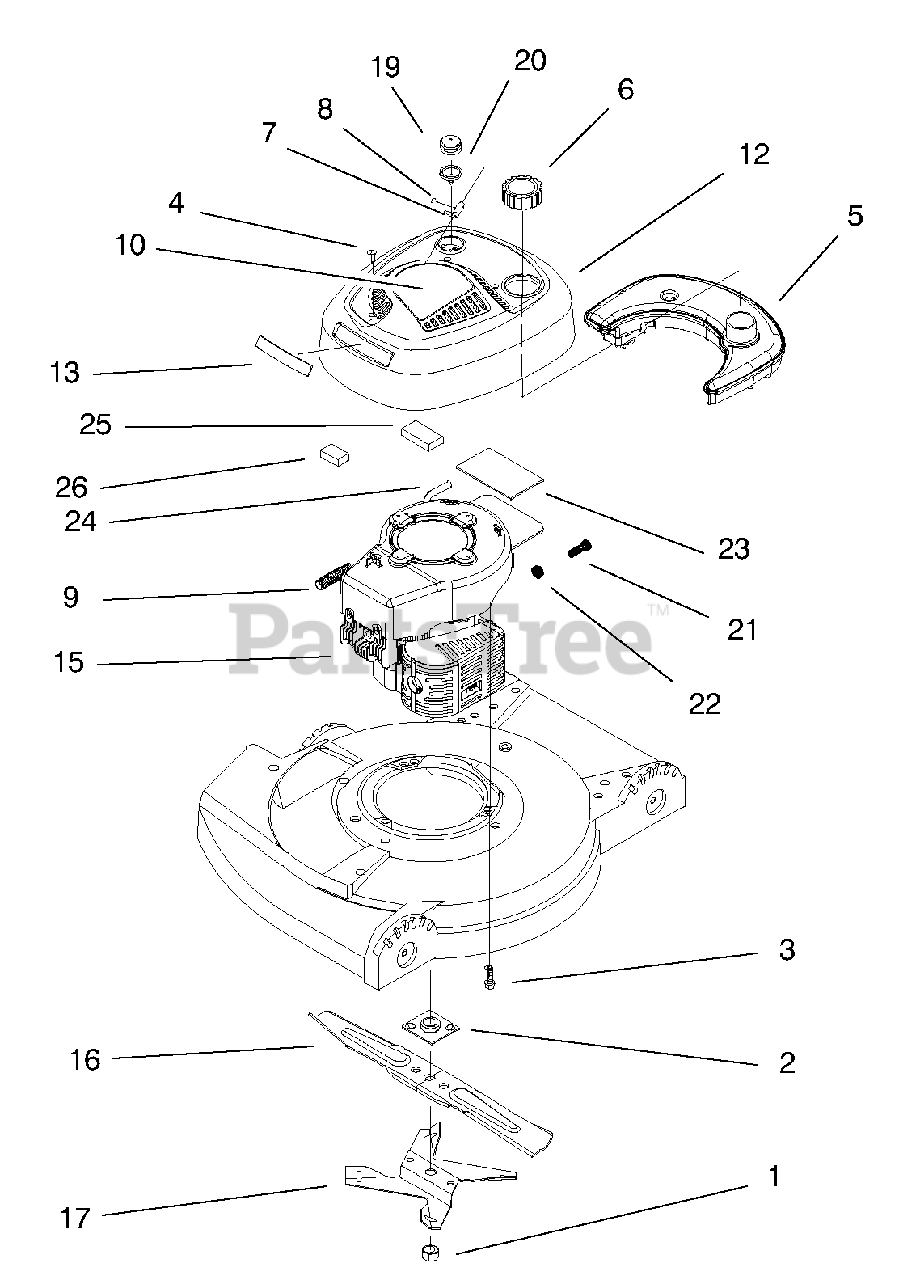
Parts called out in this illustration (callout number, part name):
1	NUT-BLADE
2	PLATE & COLLAR ASM
3	SCREW-SEMS S
4	SCREW-SEMS, PAN
6	FUEL & OIL CAP ASM
7	STOP-ROPE
9	SPRING-COMPRESSION
10	DECAL - RECOIL
12	ASM-SHROUD/RECOIL COVER
13	APPLIQUE-SHROUD
15	Engine ASM Re Cst Hsg HP
16	Blade
17	FAN-MULCHING
19	BULB-PRIMER
20	BODY-PRIMER
22	Nut
23	PAD-FOAM S
24	LINE-FUEL
25	STRIP-FOAM
26	STRIP-FOAM
